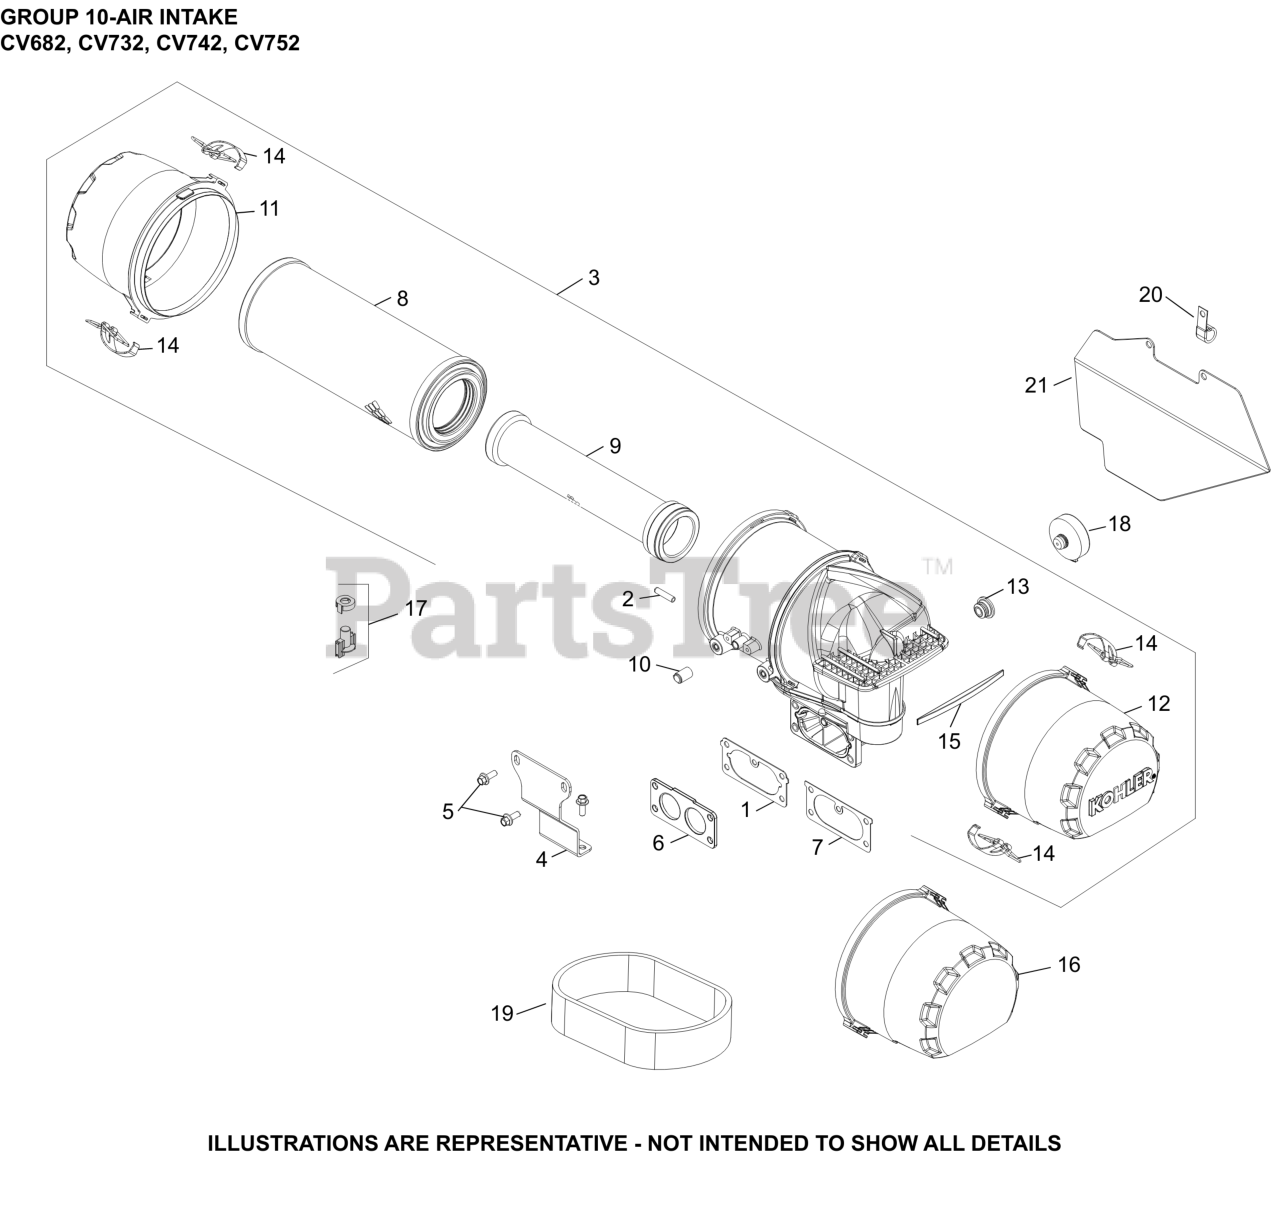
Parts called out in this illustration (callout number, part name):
1	GASKET, AIR CLEANER
2	CAP, MASKING
3	KIT, AIR CLEANER
4	BRACKET, SUPPORT
5	SCREW, FLG M6X1.0X16
8	ELEMENT, AIR FILTER - PRIMARY
9	ELEMENT, AIR FILTER - SAFETY
10	CAP, MASKING
11	COVER, AIR FILTER
12	COVER, RAIN CAP
14	CLIP ASSEMBLY
15	DAMPER, FOAM INSERT
20	CLIP, CABLE (KM)
NI	KIT, HIGH ALT(4000 TO 8000 FT)
NI	KIT, ACCEL PUMP REPAIR
NI	KIT, CARBURETOR REPAIR
NI	KIT, FLOAT BOWL REPLACEMENT
NI	KIT, FUEL SHUTDOWN SOLENOID
NI	KIT, SOLENOID
NI	KIT, CHOKE REPAIR
